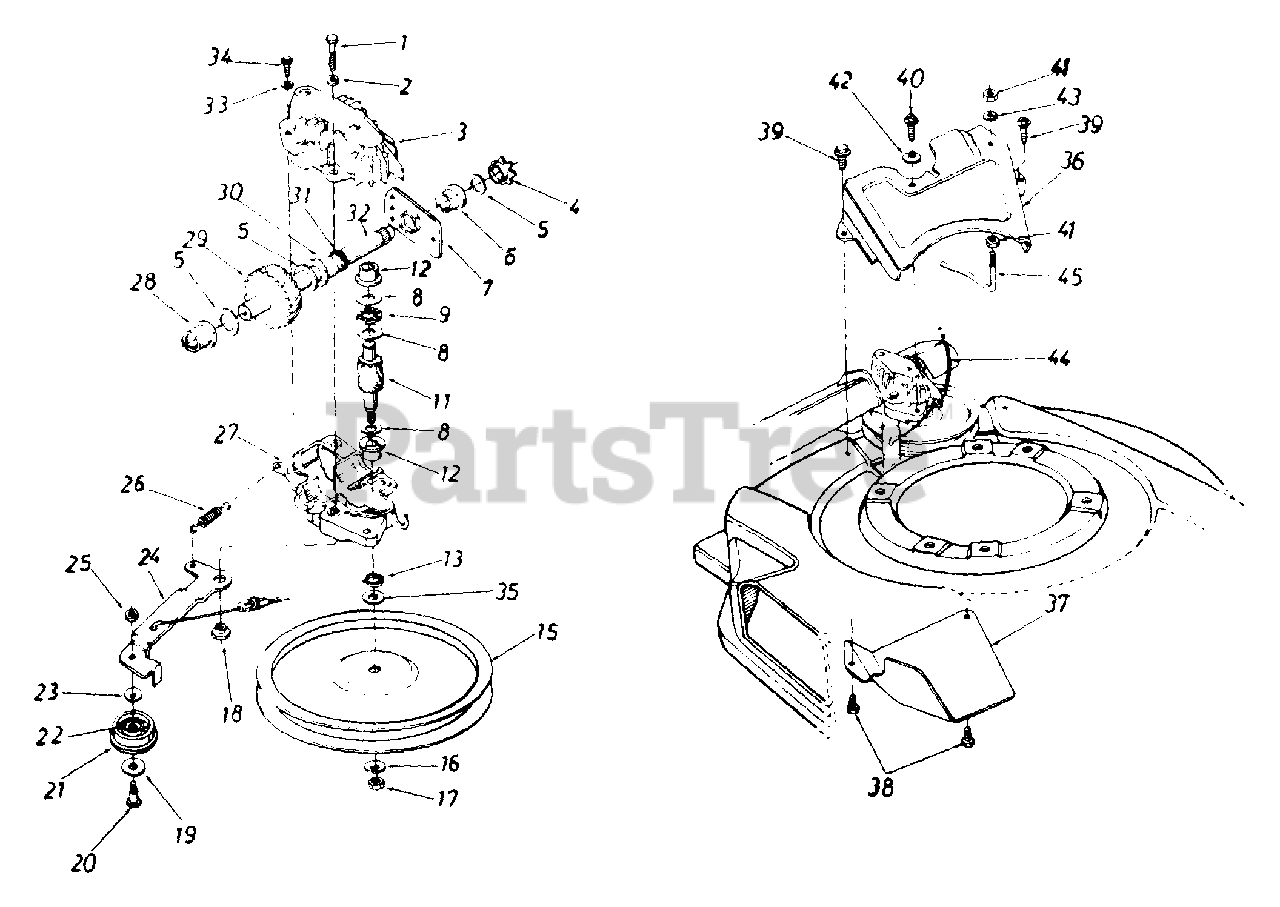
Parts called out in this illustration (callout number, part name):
1	Hex Bolt 1/4-20 x 1.25" Lg.
2	L-Wash. 1/4" I.D.
3	Upper Hsg. Half
4	#48 Sprocket 7 Tooth x 1/2 Pitch
5	Fl-Wash. 5/8" I.D. x .030
6	Hex Flange Brg..631" I.D.
8	Thrust Wash..382" I.D. x .70" O.D.
9	Thrust Bearing .375" I.D. x .812" O.D.
11	11 Tooth Helical Gear
12	Flange Bearing
13	Oil Seal
15	Fl-Pulley 5.06" I.D.
16	Bell-Wash..265" I.D. x .75"
17	Hex Nut 1/4-28 L.H. Thd.
18	Shld. Spacer .375" Dia. x .170
19	Fl-Wash..390" I.D. x 1.0"
20	Shld. Bolt .375" Dia. x .40"
21	Fl-Idler Plastic 1.50" Dia.
22	Needle Brg..375" x .375"
23	Bell-Wash..265" I.O. x .75"
24	Idler Brk't. Ass'y.
25	Hex Patch L-Nut 1/4-28 Thd.
26	Extension Spring 1.12" Lg.
27	Lower Hsg. Half
28	Flange Bearing .56 Dia.
29	33 Tooth Helical Gear
30	Flange Bearing .629 Dia.
31	Oil Seal .625 Dia.
32	Gear Sprocket Shaft
33	L-Wash. 410 I.D.
34	Hex B-Tap Scr. #10 x .62"
35	Hex Washer .26" x .88"
39	Hex AB-Tap Scr. 1/4 x .50" Lg.
40	Hex B-Tap Scr. 1/4 x .62" Lg.
41	Hex Nut 1/4-20 Thd.
42	Bell-Wash..265" I.D. x .75"
43	L-Wash. 1/4" I.D.
44	S.P. Cable - 48" Lg.
45	S.P. Belt Guards
